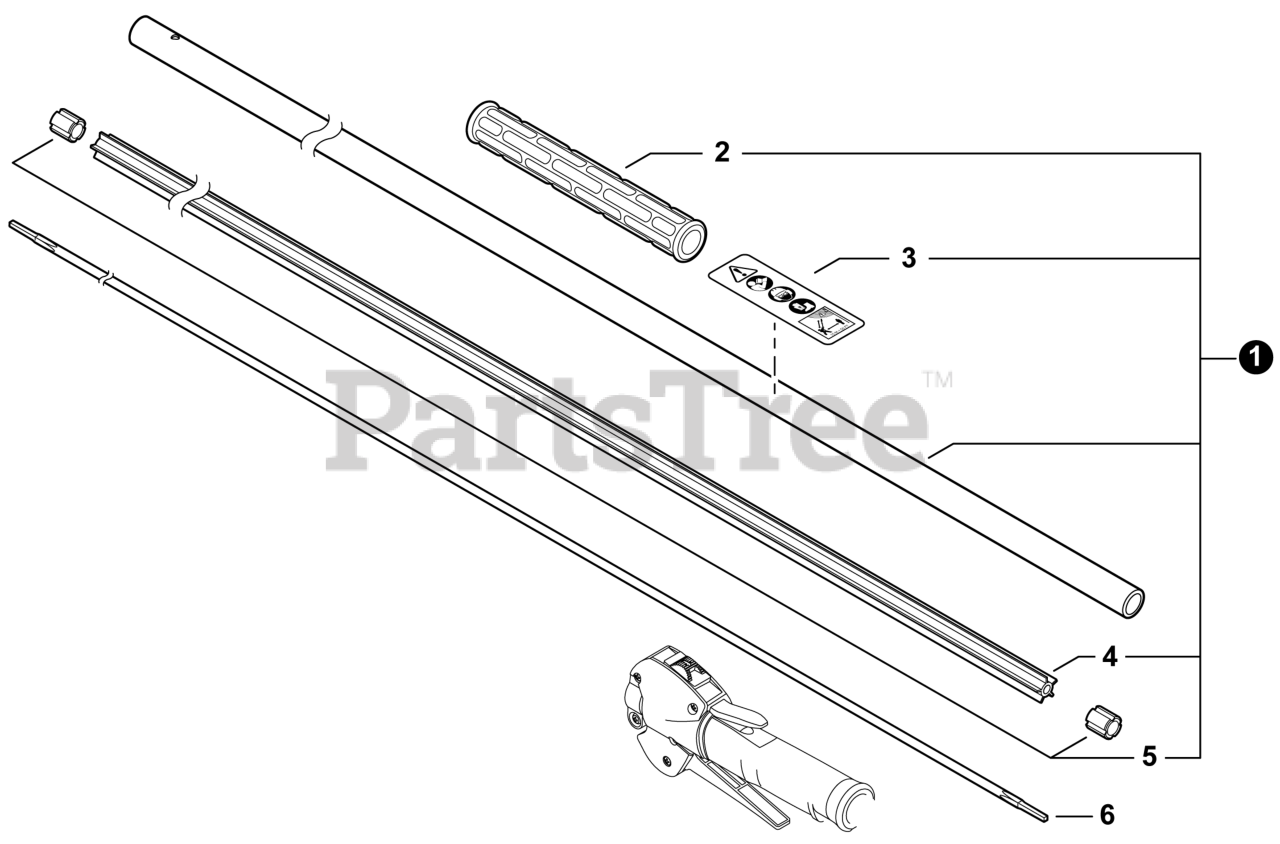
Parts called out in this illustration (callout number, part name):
1	MAIN PIPE ASSY
2	GRIP, FRONT
3	LABEL - CAUTION
4	LINER - FLEXIBLE
6	DRIVESHAFT - FLEXIBLE
